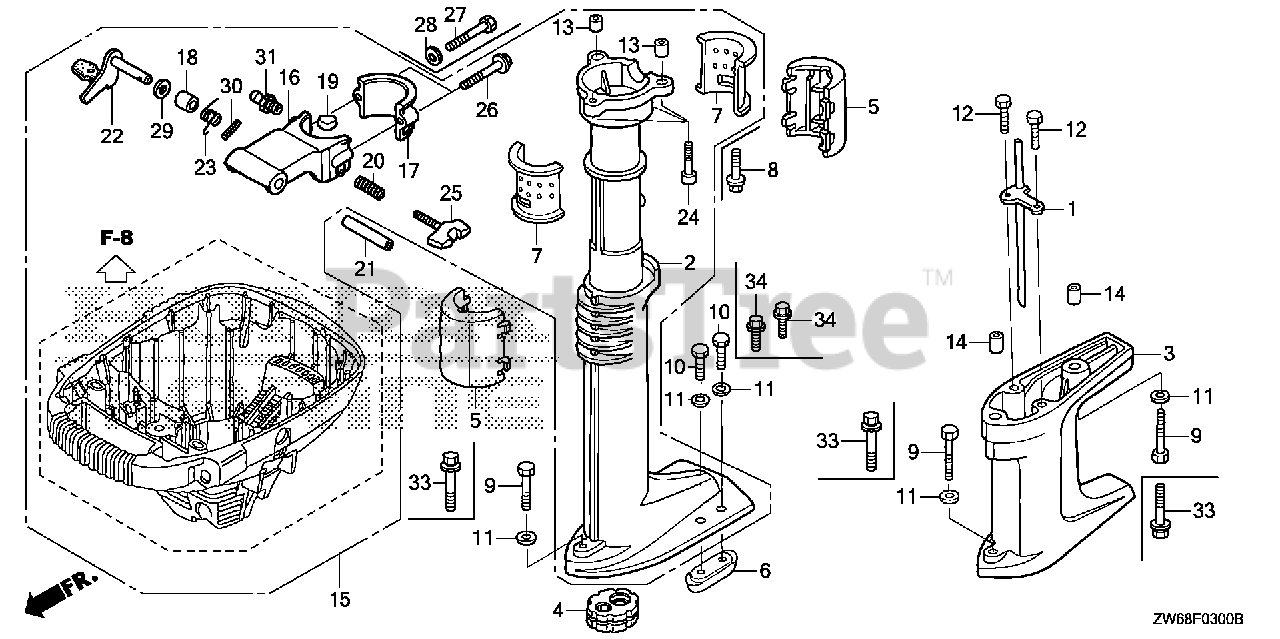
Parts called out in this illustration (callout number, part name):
2	CASE, EXTENSION *NH246* (LOOSY GRAY)
2	CASE, EXTENSION *NH246* (LOOSY GRAY) (NA USE ALT:04402-ZW6-000ZA)
4	BUSH, VERTICAL SHAFT (S)
5	PROTECTOR, EXTENSION
6	METAL, ANODE
7	LINER, SWIVEL CASE
8	BOLT, FLANGE (6X25)
8	BOLT-WASHER, SOCKET (6X30)
9	BOLT, HEX. (6X35)
10	BOLT, HEX. (6X16)
11	WASHER, PLAIN (6MM)
13	PIN, DOWEL (8X10)
15	CASE KIT, EXTENSION *NH246* (LOOSY GRAY)
16	CASE, SWIVEL *NH246* (LOOSY GRAY)
17	CAP, SWIVEL CASE *NH246* (LOOSY GRAY)
18	COLLAR, SWIVEL CASE
19	BLOCK, FRICTION
20	SPRING, FRICTION ADJUSTING
21	COLLAR, DISTANCE
22	ARM, TILT LOCK
23	SPRING, TILT LOCK
24	BOLT-WASHER, SOCKET (6X30)
25	BOLT, SWIVEL CASE
26	BOLT, FLANGE (8X35)
27	BOLT, HEX. (8X40)
28	WASHER, PLAIN (8MM)
29	WASHER, PLAIN (8MM)
30	PIN, SPRING (2.5X20)
31	NIPPLE, GREASE
33	BOLT-WASHER (6X35)
34	BOLT, FLANGE (6X16) (SUS)
